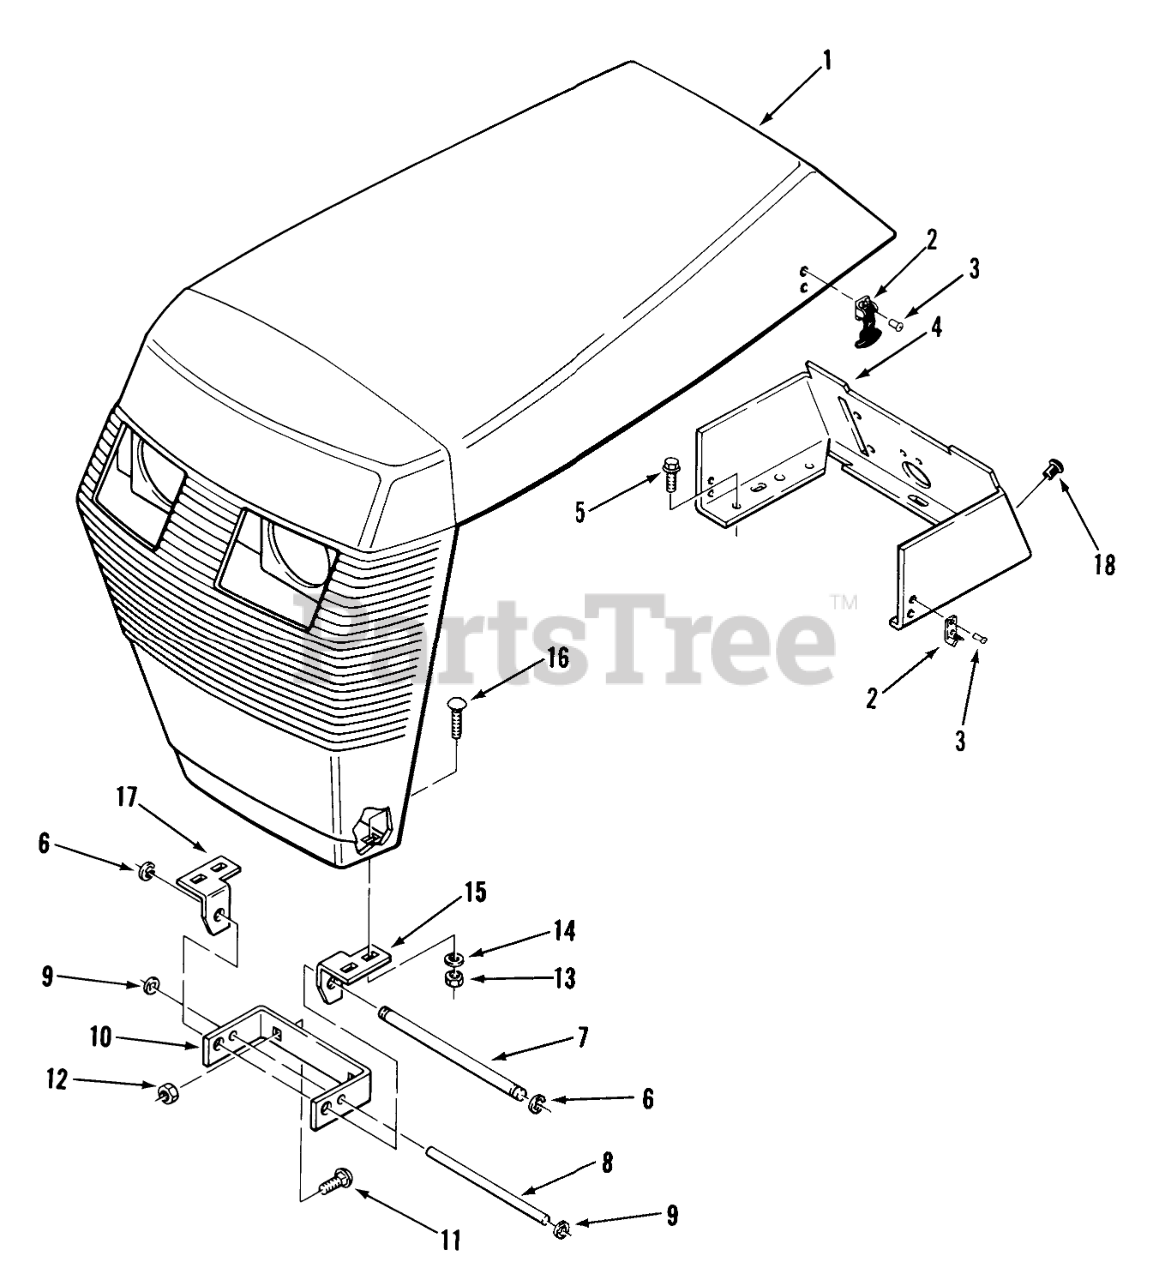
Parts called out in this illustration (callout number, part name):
1	Hood LT-1100 Only
1	Hood LT-1600 Only
2	ASSY-FLEX DRAW LATCH
3	RIVET -4
4	Console
5	SCREW
6	RING-RETAINING
7	ROD-GRILL PIVOT
8	ROD-HOOD STOP
9	SPEED NUT
10	Bracket Hood Pivot
11	Bolt-Carriage
12	Nut
13	Nut
15	BRKT-GRILL PIVOT R (NS)
16	Bolt-Carriage
16	Bolt
17	BRKT-GRILL PIVOT R
18	NYLON PLUG
